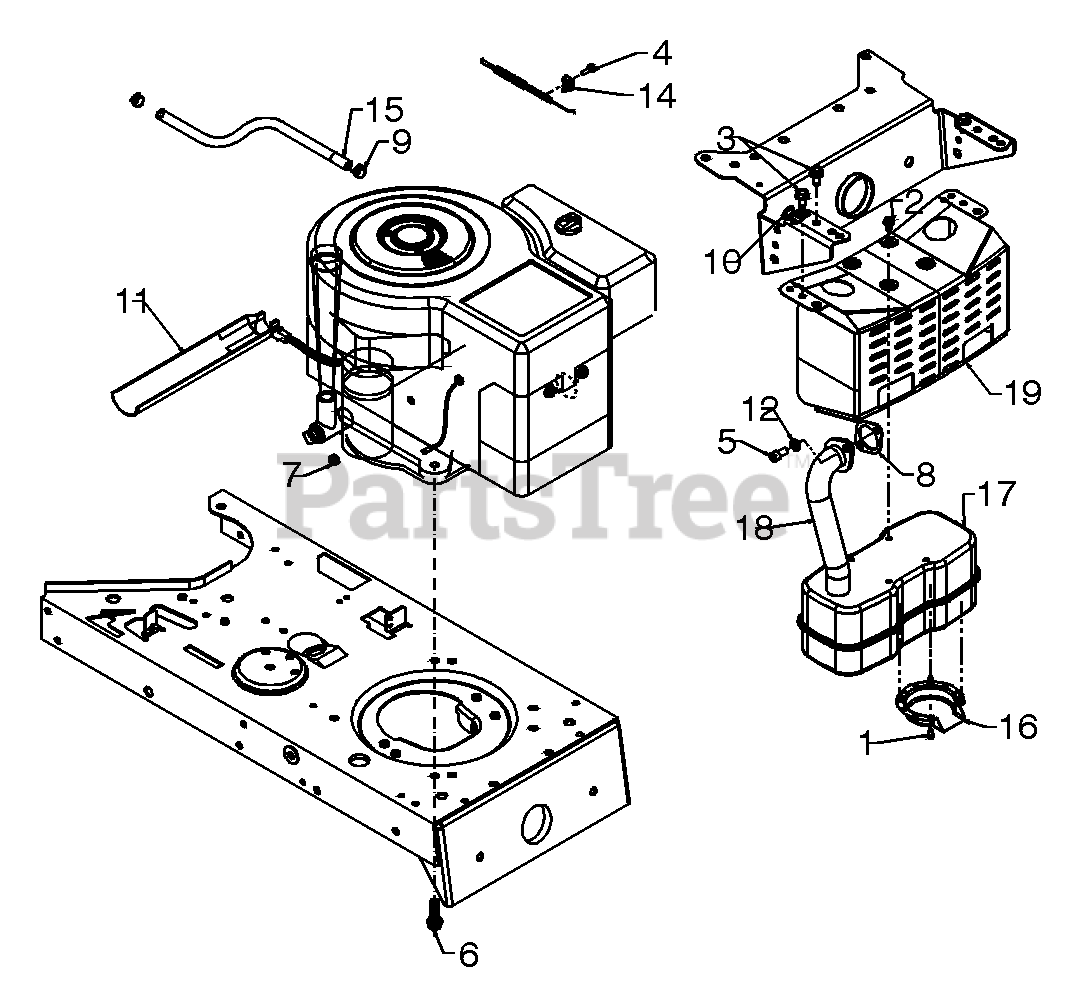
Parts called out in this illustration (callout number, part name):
1	Hex Slot Scr. #8-32 x .38" Lg.
2	Hex Wash. TT-Tap Scr. 1/4-20 x .5"
3	Hex Washer TT-Tap Scr. 5/16-18 x .62"
4	Scr. #10-32: .620 Hx. Slot Wash.
5	Socket Hd. Bolt 5/16-18 x .62" Lg.
6	Scr. 3/8-16 x 1.25
7	Nut, Hex 1/4-20
8	Exhaust Gasket
9	Hose Clamp .49 Dia.
10	Clamp 9/16 Dia.
11	Oil Drain Sleeve
12	L-Wash. 5/16" I.D.
14	Casing Clamp, Throttle, B&S
15	Fuel Line Hose
16	Muffler Deflector
17	Muffler
18	Exhaust Pipe
